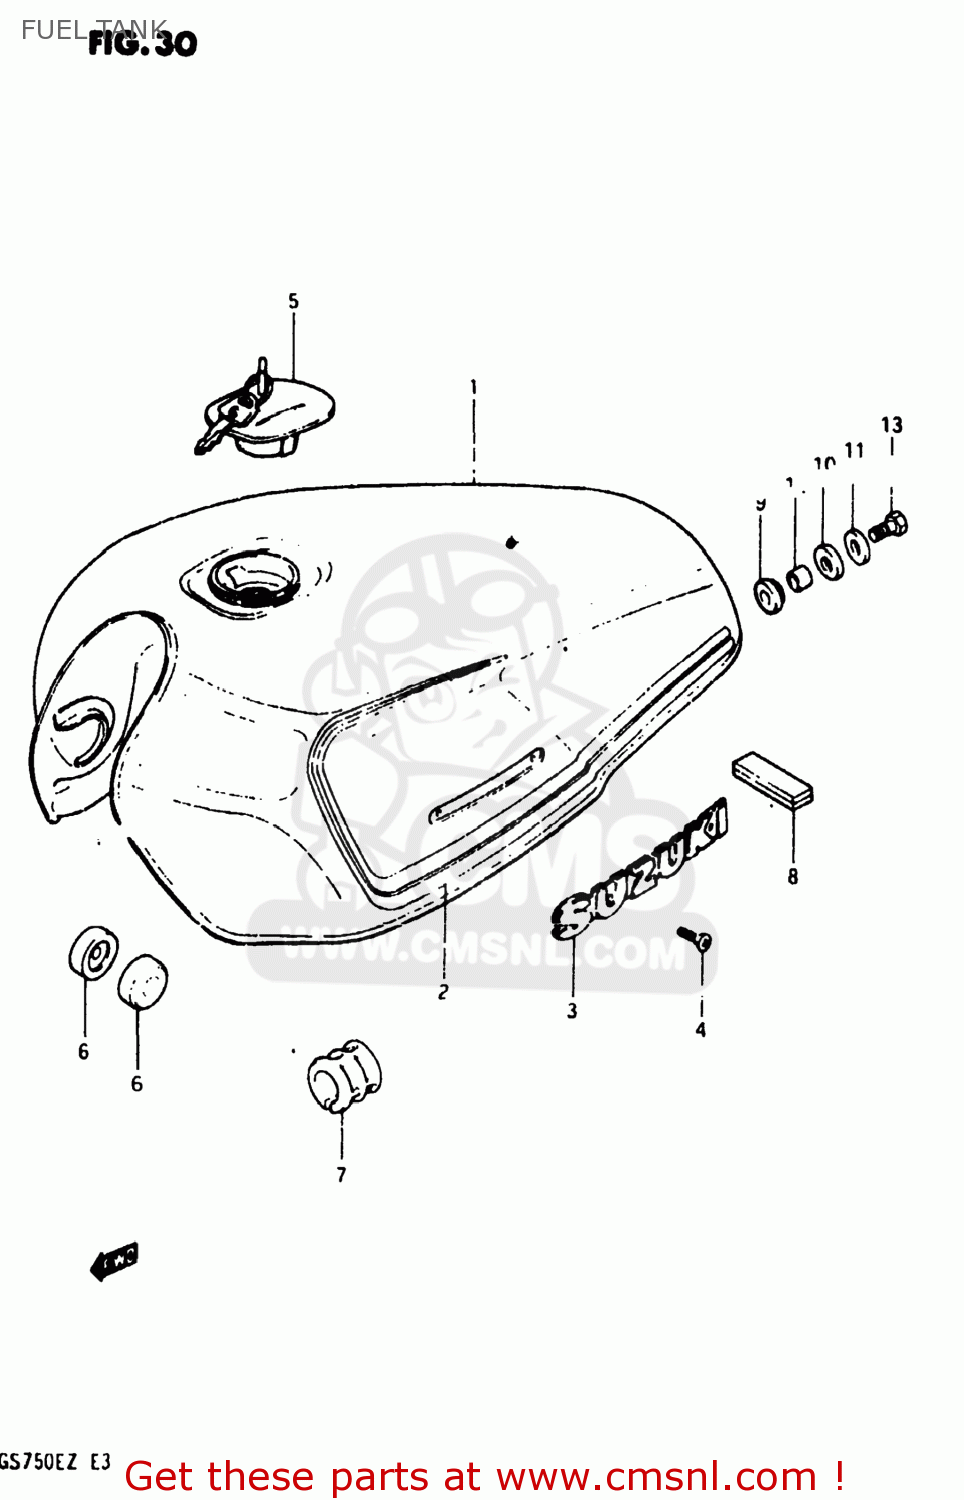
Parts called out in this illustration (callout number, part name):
1	TANK ASSEMBLY,FUEL
2	TAPE SET,FUEL TANK
3	EMBLEM,FUEL TANK
4	SCREW 3X6
5	CAP SET,FUEL TANK
6	CUSHION
7	CUSHION,FUEL TANK,UPPER
8	CUSHION
9	CUSHION
10	CUSHION
11	WASHER (8.5X29X1.6)
12	SPACER(8.5X12X19)
13	BOLT (8X30)
